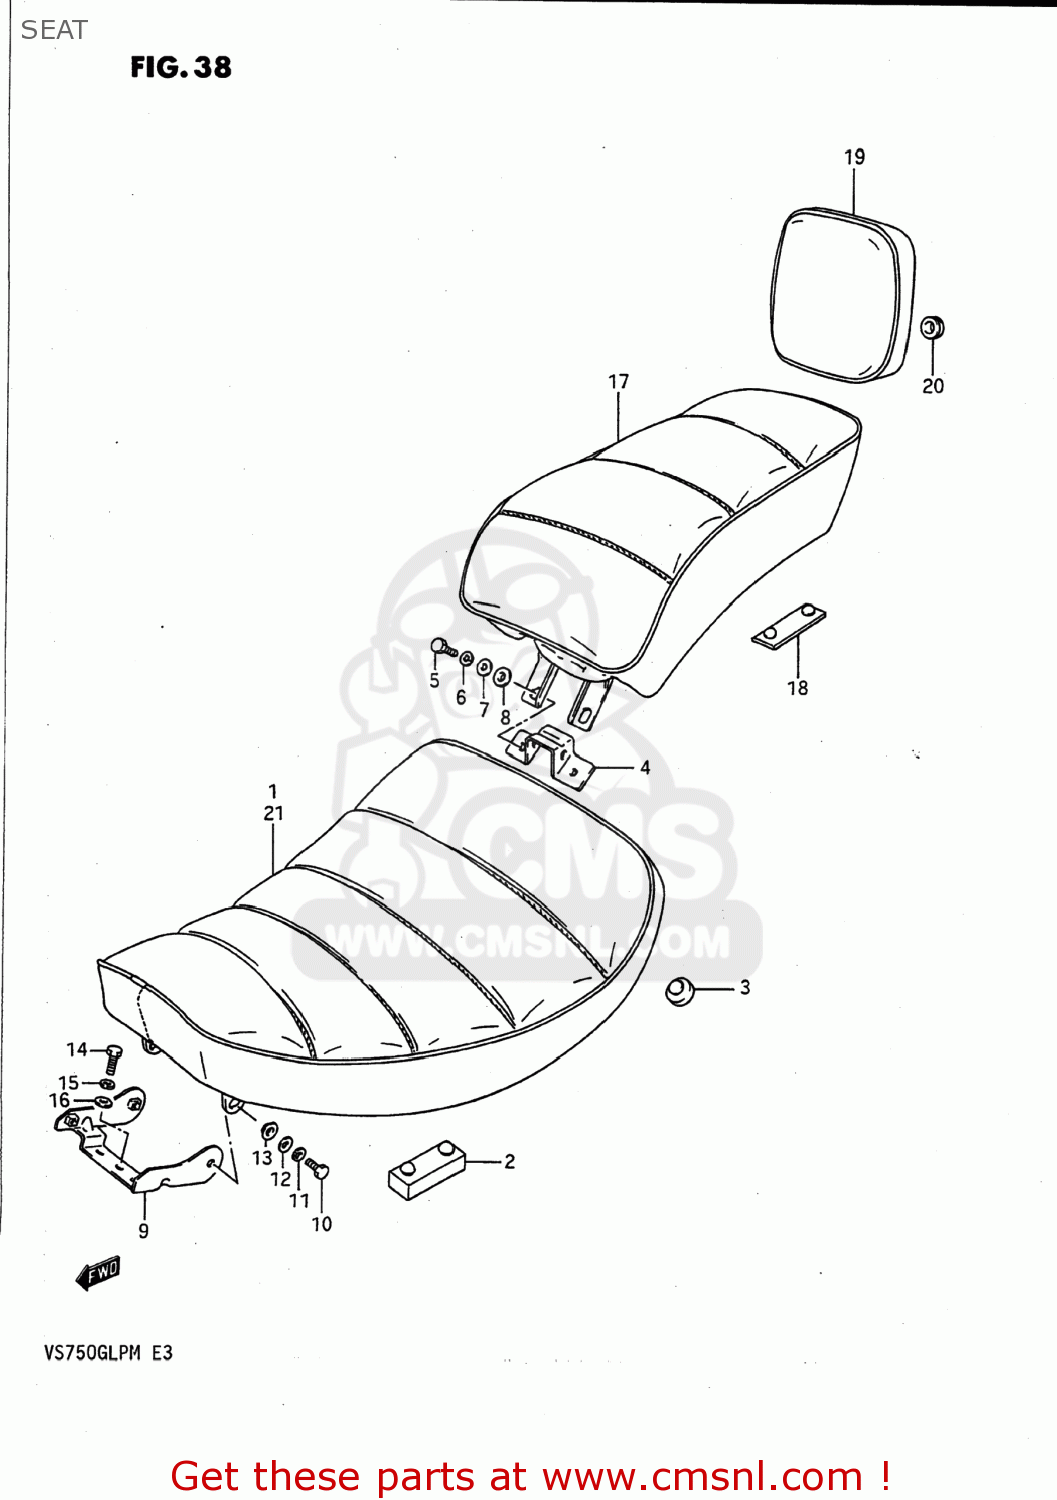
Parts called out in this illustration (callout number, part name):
1	SEAT ASSEMBLY
2	CUSHION,SEAT
3	CUSHION
4	PLATE,FR SEAT HOOK & RR
5	BOLT
6	WASHER,LOCK
7	WASHER, LOWER
8	WASHER
9	BRACKET,SEAT,FRONT
10	BOLT
11	WASHER,LOCK
12	WASHER, LOWER
13	WASHER
14	BOLT
15	WASHER,LOCK
16	WASHER, LOWER
17	SEAT ASSEMBLY,PILLION
18	CUSHION
19	PAD ASSEMBLY,SEAT
20	CUSHION
21	SEAT ASSEMBLY
